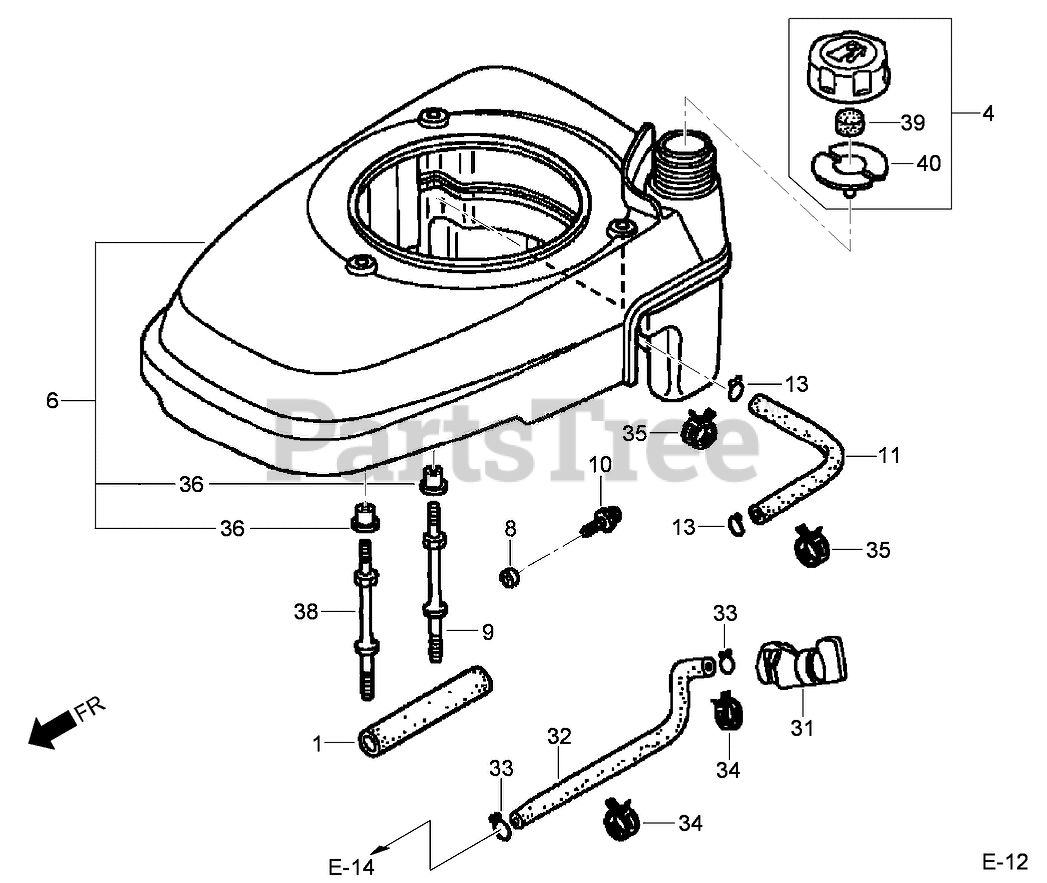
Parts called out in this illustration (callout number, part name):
1	SUPPORTER-RUBBER (107 mm)
4	FUEL TANK CAP ASM
6	COVER-FAN, N H1 (BLACK)
8	COLLAR-TURN SIGNAL, FRONT
9	BOLT-STUD (H=42.5MM)
10	SCREW-WASHER (5X10)
11	TUBE-FUEL (5.3X150) (FKM) (engine serial numbers starting at 3698327)
11	HOSE-FUEL, BULK (5.5X3000) (5.5X100) (engine serial numbers up to 3698326)
13	CLIP-TUBE (B10) (engine serial numbers up to 3698326)
31	PETCOCK ASM
32	TUBE-FUEL (engine serial numbers up to 3698326)
32	TUBE-FUEL (FKM) (engine serial numbers starting at 3698327)
33	CLIP-TUBE (B8) (engine serial numbers up to 3698326)
34	CLAMP-TUBE (D8) (engine serial numbers starting at 3698327)
35	CLAMP-TUBE (D10) (engine serial numbers starting at 3698327)
36	COLLAR-COVER, FAN
38	BOLT-STUD (H=42.5MM)
39	SPONGE-BREATHER, FUEL CAP
40	GASKET-CAP, FUEL
